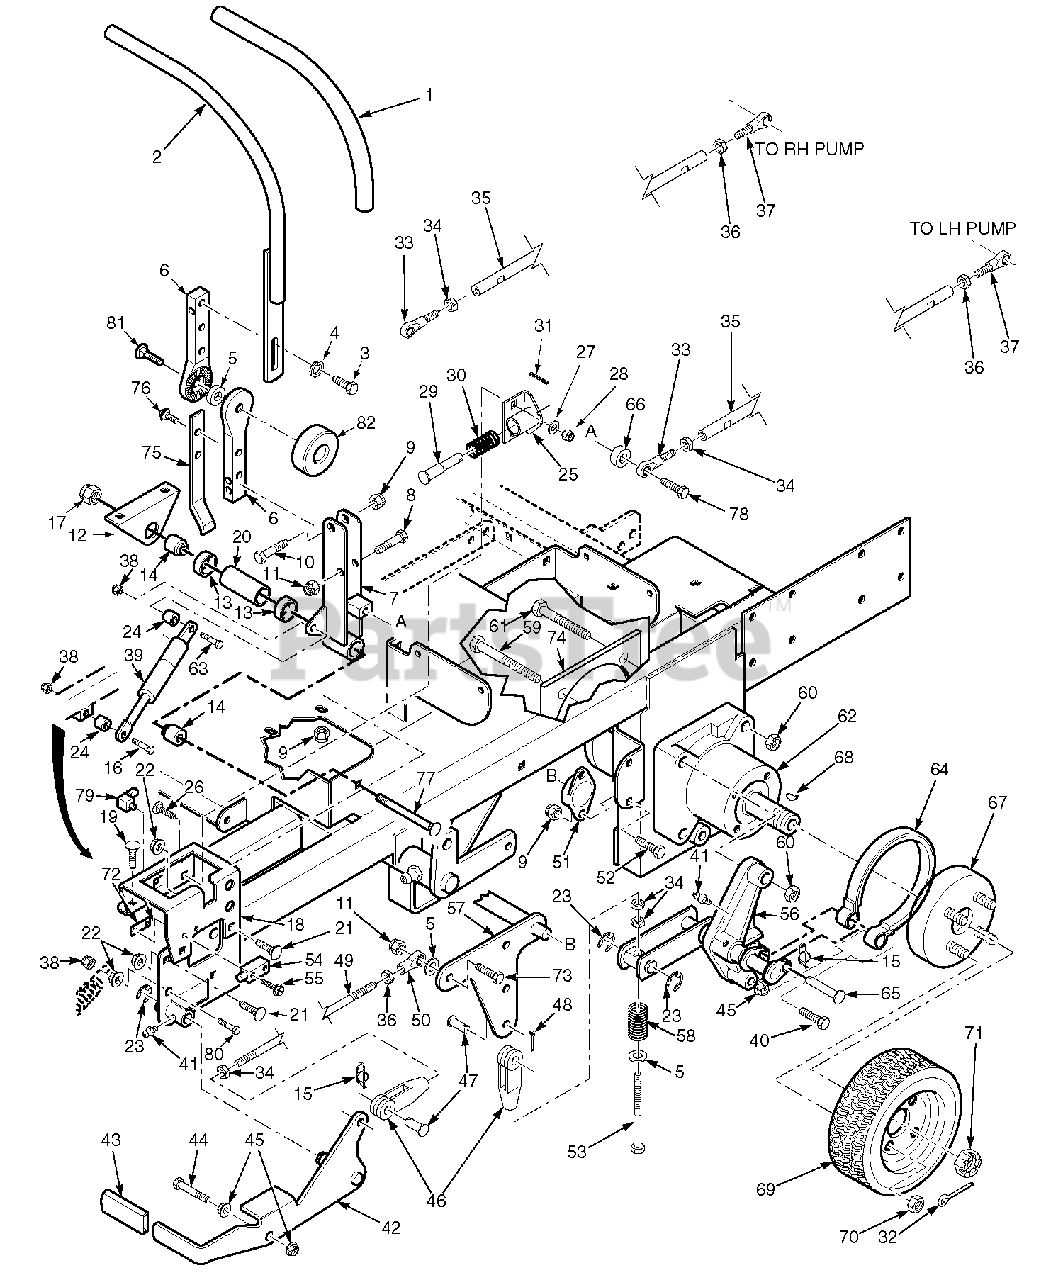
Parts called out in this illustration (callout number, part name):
1	Grip, Handle Bar
2	Handle Bar, LH
2	Handle Bar, RH
3	Bolt, Hex Head 5/16-18 x 1"
4	Lockwasher, 5/16"
5	Rubber Spacer
6	Bar, Control Lever
7	Control Lever Weldment, LH
7	Control Lever Weldment, RH
8	Bolt, Hex Head 5/16-18 x 2"
9	Nut, Hex Elastic Stop 5/16-18
10	Bolt, Hex Head 3/8-16 x 2"
11	Nut, Hex Elastic Stop
12	Mount, Control Linkage
13	Ball Bearings, Neutral Return
14	Spacer
15	Pin, Rue Cotter 3/8" Dia.
16	Bolt, Hex Head, 5/16-18 x 2.75" Zinc
17	Nut, Hex Elastic Stop 5/8-11
18	Bracket, Control Lever LH
18	Bracket, Control Lever RH
19	Bolt, Carriage 5/16-18 x 1"
20	Spacer, Bearing
21	Bolt, Carriage 5/16-18 x 3/4"
22	Nut, Hex Serrated Flange 5/16-18
23	Ring, Retaining 5/8" External "E"
24	Spacer
25	Bracket, Neutral Return
26	Bolt, Carriage 1/4-20 x 3/4"
27	Flatwasher, 1/4" (.312 x .750 x .065")
28	Nut, Hex Elastic Stop 1/4-20
29	Pin, Retaining Spring
30	Spring
31	Roll Pin, Spring 5/32" x 3/4"
32	Pin, Cotter 9/16" x 1-1/2"
33	Rod End, Male 3/8"-24 RH Thread
34	Nut, 3/8"-24 RH Thread
35	Tube, Control Link Air-Cooled Engine
35	Tube, Control Link Liquid-Cooled Engine
36	Nut, Hex 3/8"-24 LH Thread
37	Rod End, Male 3/8"-24 LH Thread
38	Locknut, 5/16-18, Elastic Stop
39	Gas Damper
40	Bolt, Hex Head 1/2-13 x 2-1/2"
41	Grease Fitting
42	Lever, Parking Brake
43	Grip, Parking Brake
44	Bolt, Hex Head 3/8-16 x 2-3/4"
45	Nut, Hex Serrated Flange 1/2-13
46	Clevis, Traction Control
47	Pin, Clevis 3/8-16 x 1-1/16"
48	Pin, Cotter 3/32 x .75"
49	Rod, Parking Brake
50	Rod End, LH Thread
51	Bushing, Self Align
52	Bolt, Hex Head 5/16-18 x 3/4"
53	Bolt, Hex Hd 3/8-24 x 5-1/4", 23/4" Thrd
54	Switch
55	Screw, Hex-Slotted Washer Head #10 32 x 3/4"
56	Brake Linkage, LH
56	Brake Linkage, RH
57	Bellcrank, Brake Actuator
58	Spring
59	Bolt, Hex Head 1/2-13 x 3-3/4"
60	Locknut, Hex 1/2-13 Center Lock
61	Bolt, Hex Head 1/2-13 x 2-1/2"
62	Wheel Motor, Ross
63	Bolt, Hex Head, 5/16-18 x 1.75", Zinc
64	Brake Band Assembly
65	Pin, Clevis 3/8" Dia. x 1.93"
66	Spacer
67	Wheel Hub/Brake Drum Assembly
68	Key, Woodruff 5/16 x 1"
69	Wheel Assembly 23 x 10.5-12 (52" Only)
69	Rim W/Valve Stem (52" Only)
69	Tire, 23 x 10.5-12 (52" Only)
69	Wheel Assembly 24 x 12-12 Turf Master
69	Rim W/Valve Stem
69	Tire, 24 x 12-12 Turf Master
70	Lug Nut, 1/2-20
71	Nut, Hex Castle
72	Threaded Plate
73	Bolt, Hex Head 3/8-16 x 1-1/2"
74	Plate Weldment, Motor Backing
75	Actuator Switch
76	Bolt, Hex Serrated Flange 5/16-18 x 3/4"
77	Bolt, Carriage 3/8-16 x 4-3/4"
78	Bolt, Hex Head 3/8-16 x 1"
79	Switch
80	Bolt, Hex Head 3/8-16 x 1-1/4"
81	Bolt, Carriage 5/16-18 x 1-1/2"
